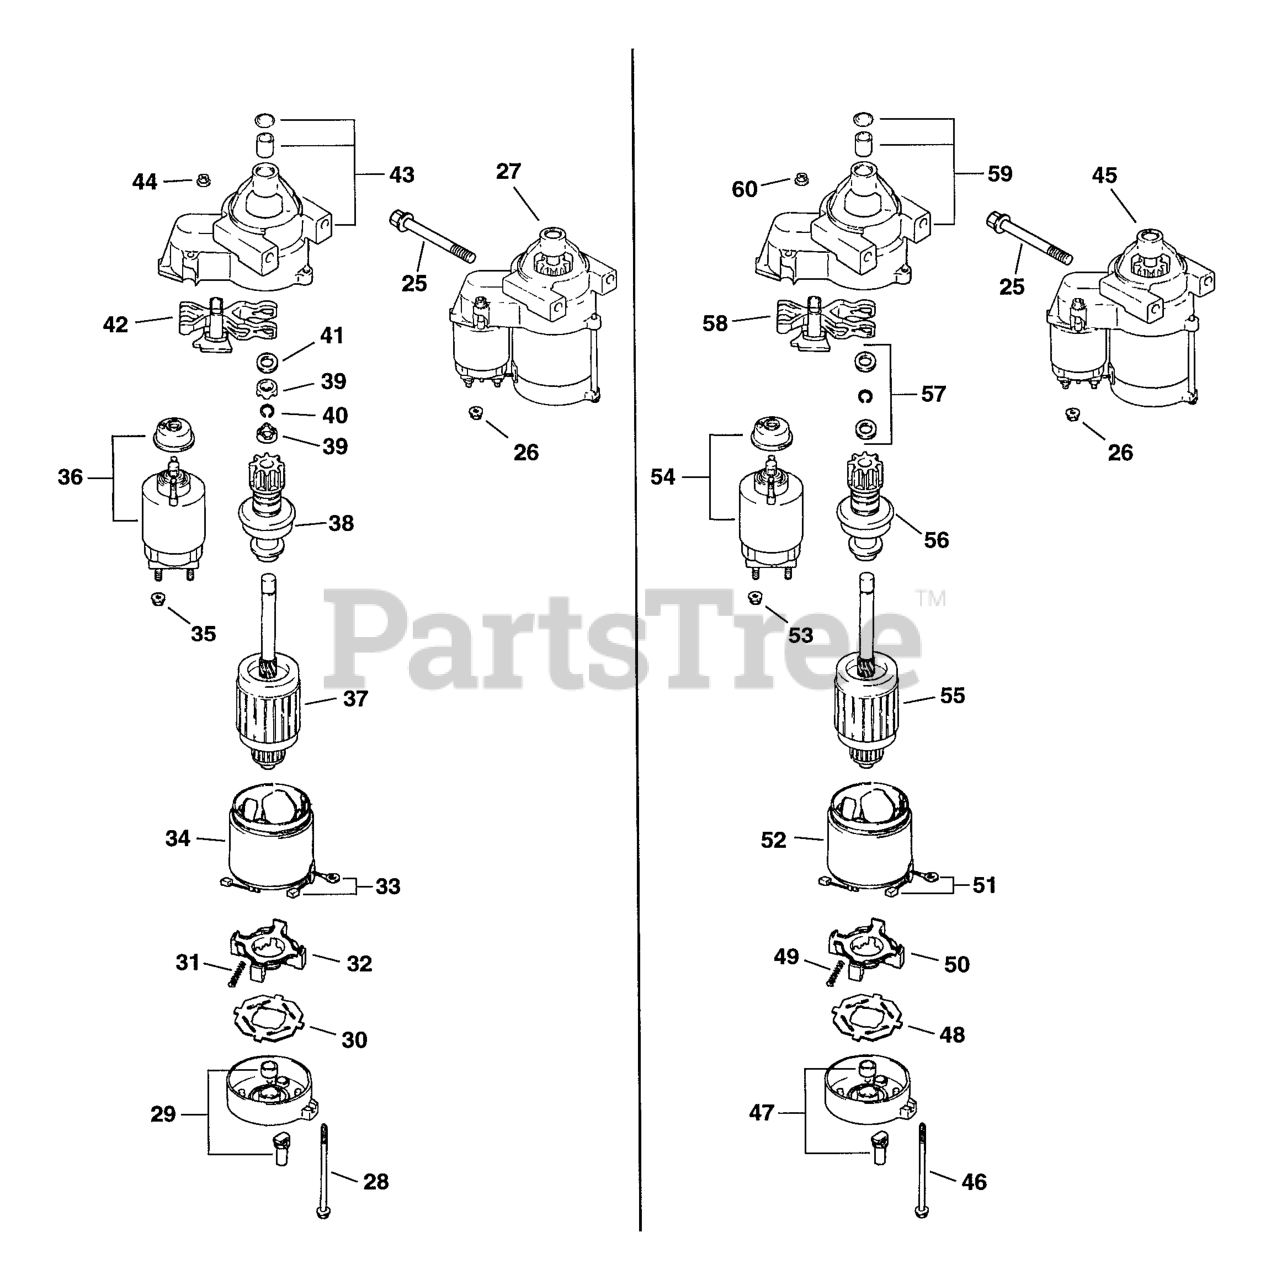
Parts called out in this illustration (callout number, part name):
27	Starter, Solenoid Shift
28	Bolt, Thru M5x0.8x99
29	Cap, Commutator End
30	Insulator
31	Spring, Brush
32	Holder, Brush
33	Kit, Brush
35	Nut, Starter
36	Solenoid
37	Armature, Starter
38	Drive, Pinion
39	Nut, Stop Collar
40	Ring, Retainer
41	Washer, Thrust
42	Lever, Starter Drive
43	Cap, Drive End
44	Nut, Starter
45	Starter, Solenoid Shift
46	Bolt, Thru M5x0.8x99
47	Cap, Commutator End
48	Insulator
49	Spring, Brush
50	Holder, Brush
51	Kit, Brush
53	Nut, Starter
54	Solenoid
55	Armature, Starter
56	Drive, Pinion
57	Kit, Starter Repair
58	Lever, Starter Drive
59	Cap, Drive End
60	Nut, Starter
